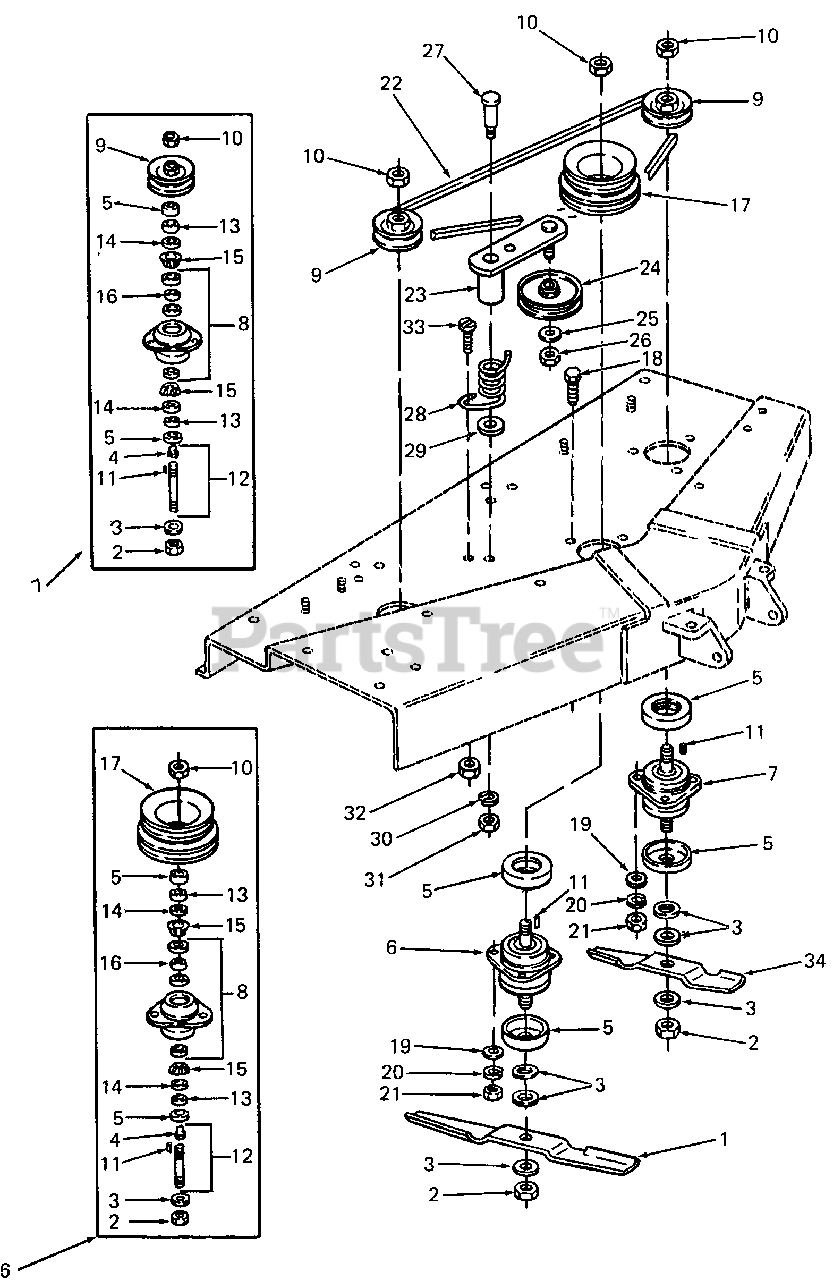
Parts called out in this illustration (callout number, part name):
1	Blade, Mower, 20.0 Lg
2	Nut, Hex, 3/4-16 GR8
3	Washer, Flat, .781 X 2.0 X .105 - Hdn
4	Fitting, Lube, 3/16
5	Cup, Spindle Hdn
6	Spindle Service Kit - Center
7	Spindle Service Kit - Outer
8	Housing, Spindle w/Cups
9	4L V-Pulley, 3.12 OD
10	Nut, Hex Jam, 3/4-16 GR5
11	Key, #91 Woodruff, 1/4 X 3/4 - Hdn
12	Shaft, Blade w/Fitting
13	Spacer, .755 X 1.25 X .44 Lg
14	Seal, Oil, 1.25 X 1.874 X .25
15	Cone, Bearing
16	Spacer, Bearing
17	Pulley, Double
18	Screw, Hex Cap, 3/8-16 X 1.0 Lg GR5
19	Washer, Flat, .378 X 1.0 X .127 Thk
20	Washer, Lock, 3/8
21	Nut, Hex, 3/8-16 GR5
22	V-Belt 4L
23	Arm Assy, Idler
24	Pulley, Flat Idler, 4.06 OD
25	Washer, Flat, .406 X .75 X .063 Thk
26	Nut, Hex Center Lock, 3/8-16 GR5
27	Bolt, Shoulder, .68 Dia X 1.56 Lg X 7/16-14
28	Spring, Torsion
29	Washer, Flat, .469 X .875 X .105 Thk
30	Washer, Lock, 7/16
31	Nut, Hex, 7/16-14 GR5
32	Nut, Hex Insert Top Lock Jam, 3/8-16
33	Screw, Truss Hd, 3/8-16 X .75 Lg
34	Blade, Mower, 10.19 Lg
